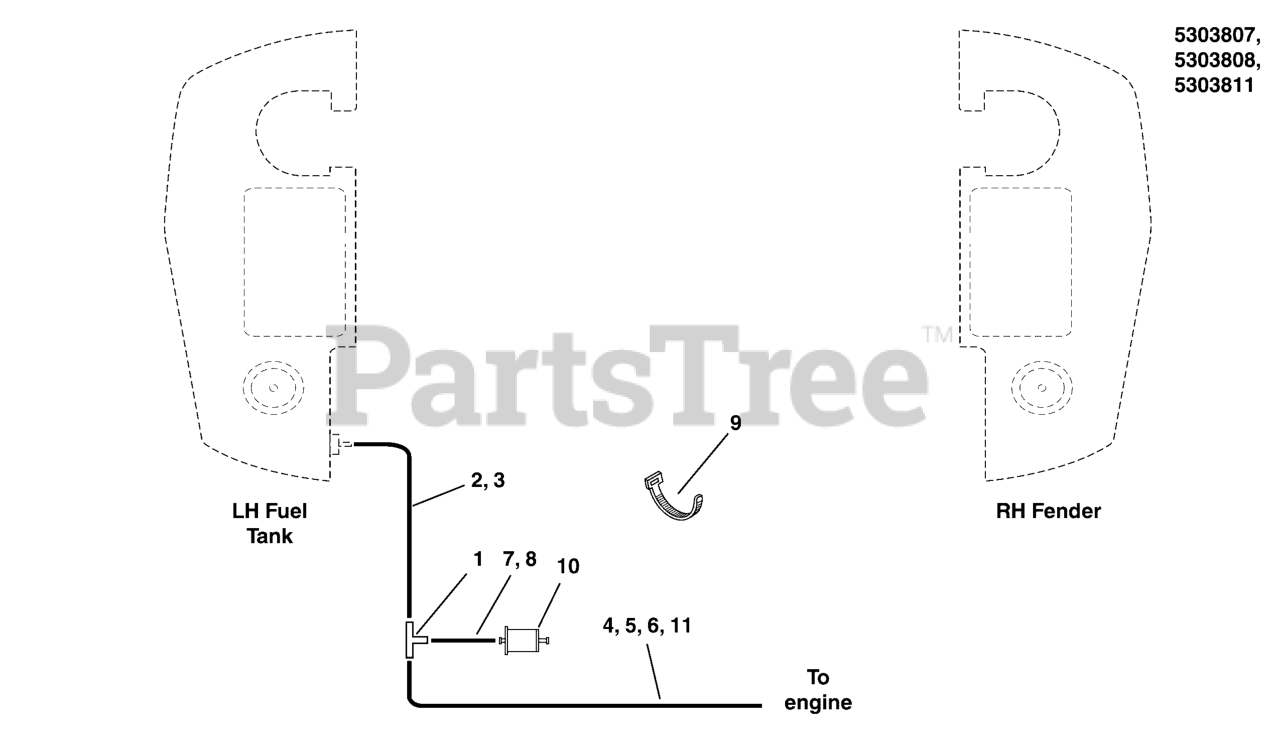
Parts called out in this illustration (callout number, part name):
1	FITTING, 3/16" TEE, BARB TYPE, HDPE
2	HOSE, VAPOR, 5MM ID, 29.00 LG
3	HOSE, VAPOR, 5MM ID, 18.00 LG
4	HOSE, VAPOR, 5MM ID, 12.00 LG
5	HOSE, VAPOR, 5MM ID, 16.00 LG
6	HOSE, VAPOR, 5MM ID, 20.50 LG
7	HOSE, VAPOR, 5MM ID, 2.00 LG
8	HOSE, VAPOR, 5MM ID, 16.00 LG
9	TIE,SELF-LOCKING, 6"
10	FILTER, FUEL
11	HOSE, VAPOR, 5MM ID, 21.00 LG
